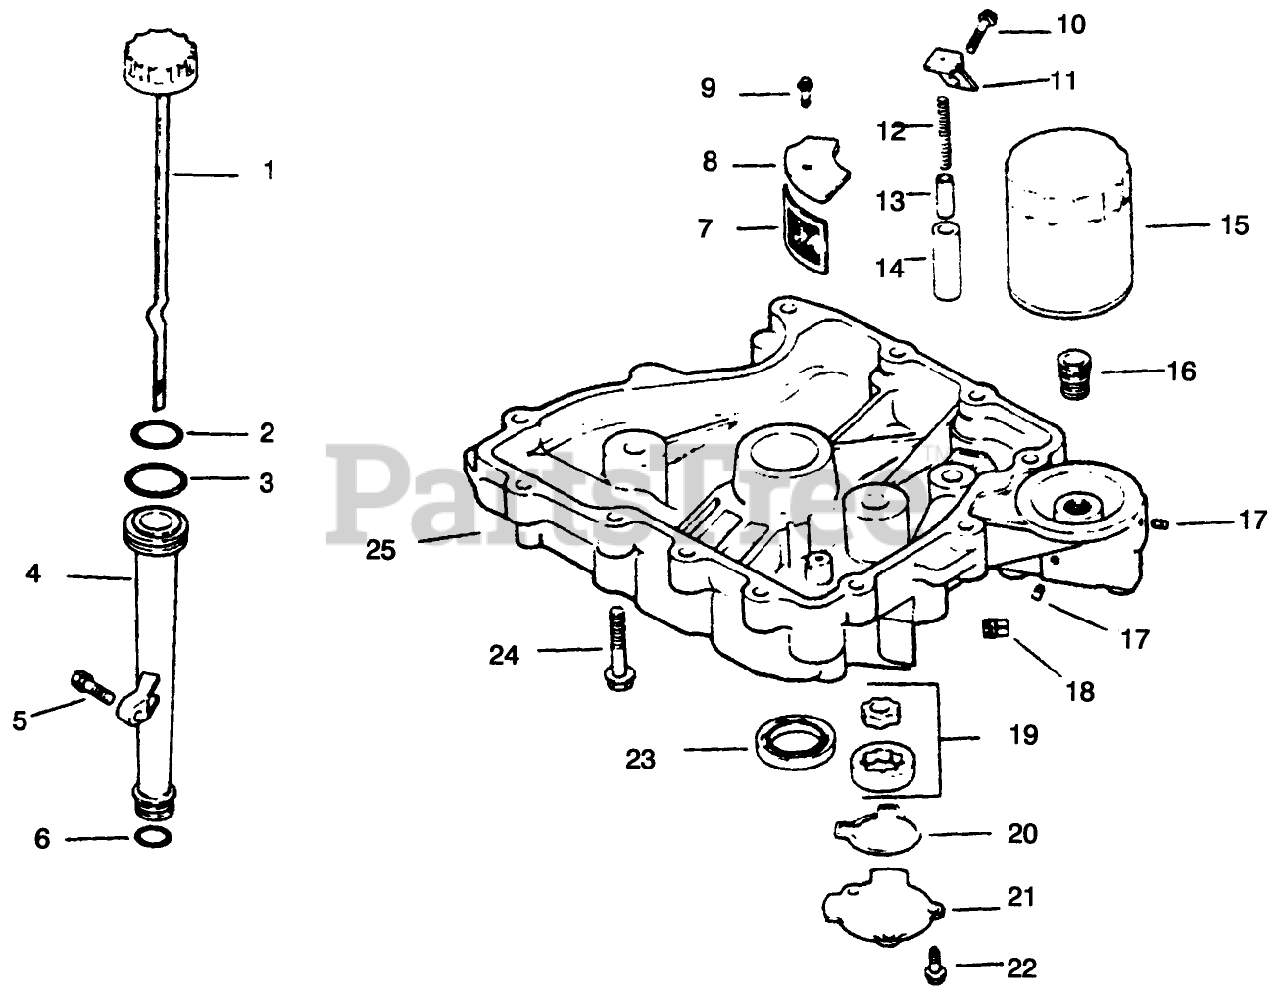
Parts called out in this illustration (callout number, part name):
1	Screw
2	Starter (Incl.Ref. #3-9)
3	Housing-Starter
4	Handle
5	Rope-Starter
6	Spring & Keeper
8	Kit-Dog Replacement (Incl Ref. #9)
9	Screw-Pozidrive
10	Cup-Driver
